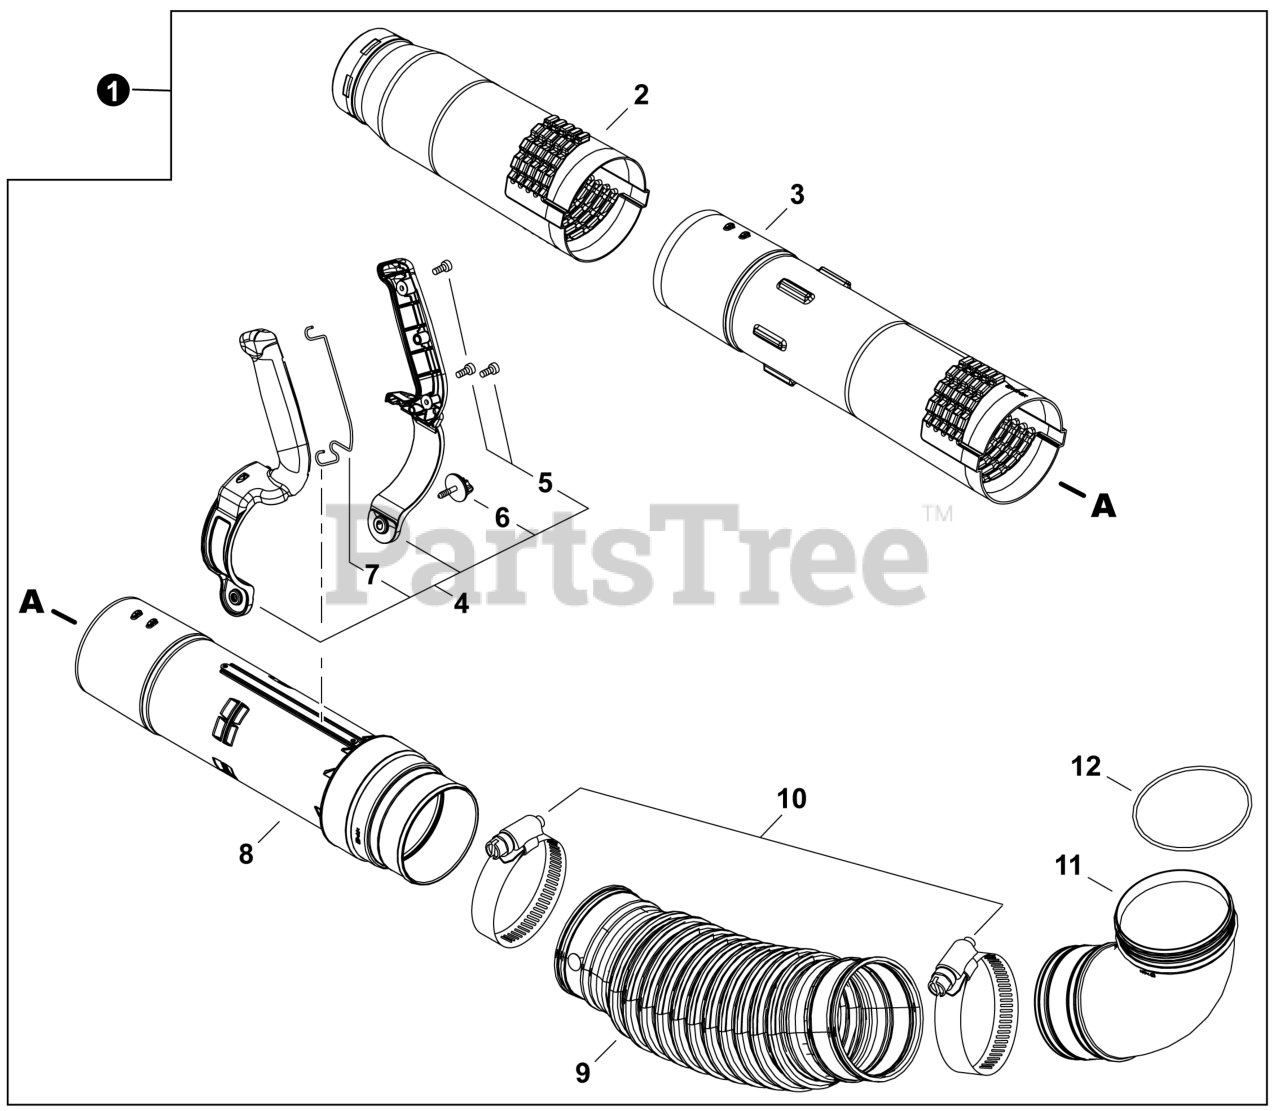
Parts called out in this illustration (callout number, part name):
1	TUBE KIT, BLOWER, HIP MOUNT
2	TUBE, BLOWER - NOZZLE
3	TUBE, BLOWER - STRAIGHT
4	HANDLE KIT - BLOWER TUBE
5	BOLT, TORX 4x12
6	KNOB, FASTENER
7	PLATE, GROUND
8	TUBE, BLOWER - SWIVEL
9	TUBE, BLOWER - FLEXIBLE
10	CLAMP - BAND
11	TUBE, BLOWER - ELBOW
